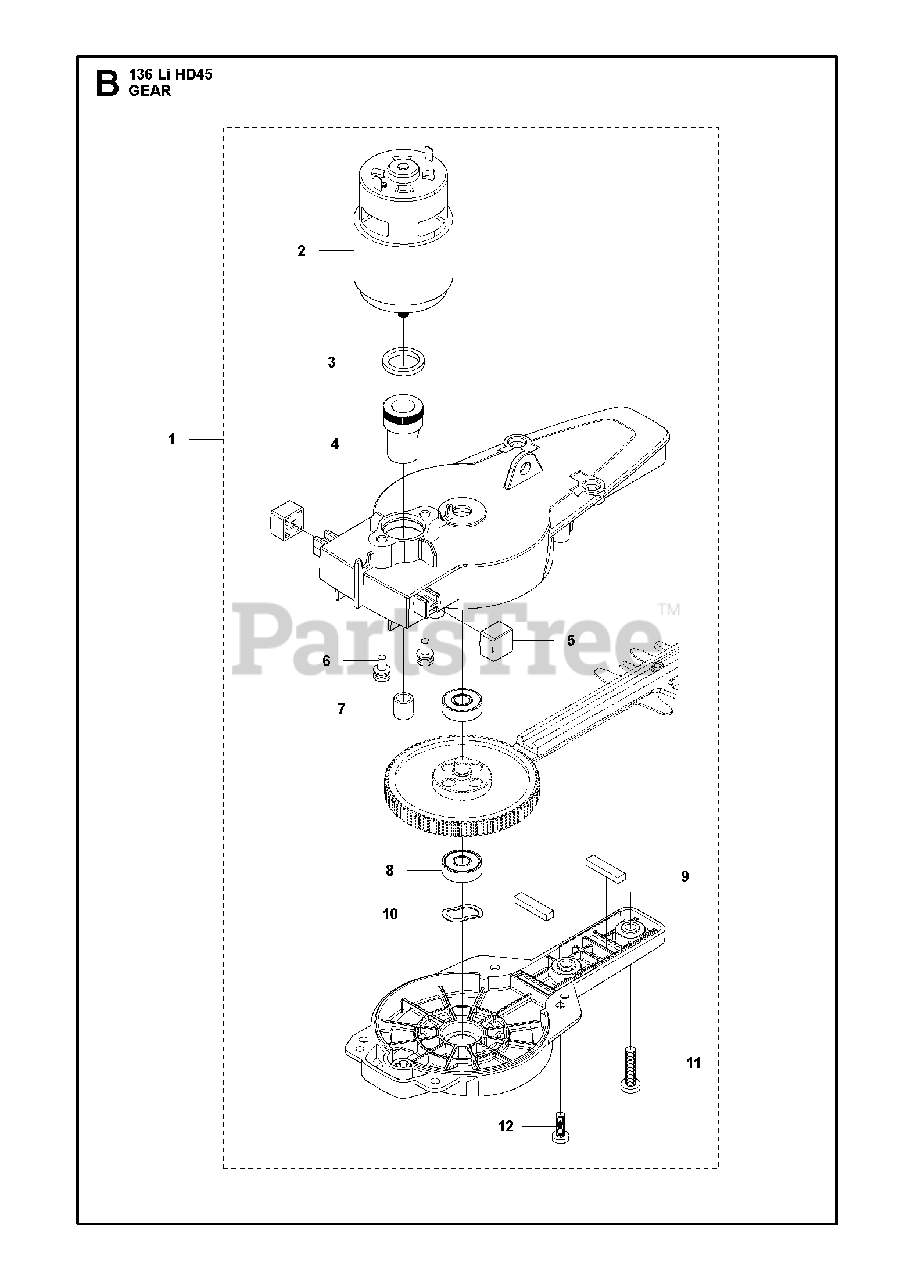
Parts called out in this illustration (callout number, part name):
1	GEAR BOX ASSEMBLY
5	SHOCK ABSORBING
7	NEEDLE BEARING
8	BALL BEARING
9	PAD DUSTPROOF
10	SPRING WASHER
11	SCREW M5X20
12	SCREW M4X12
